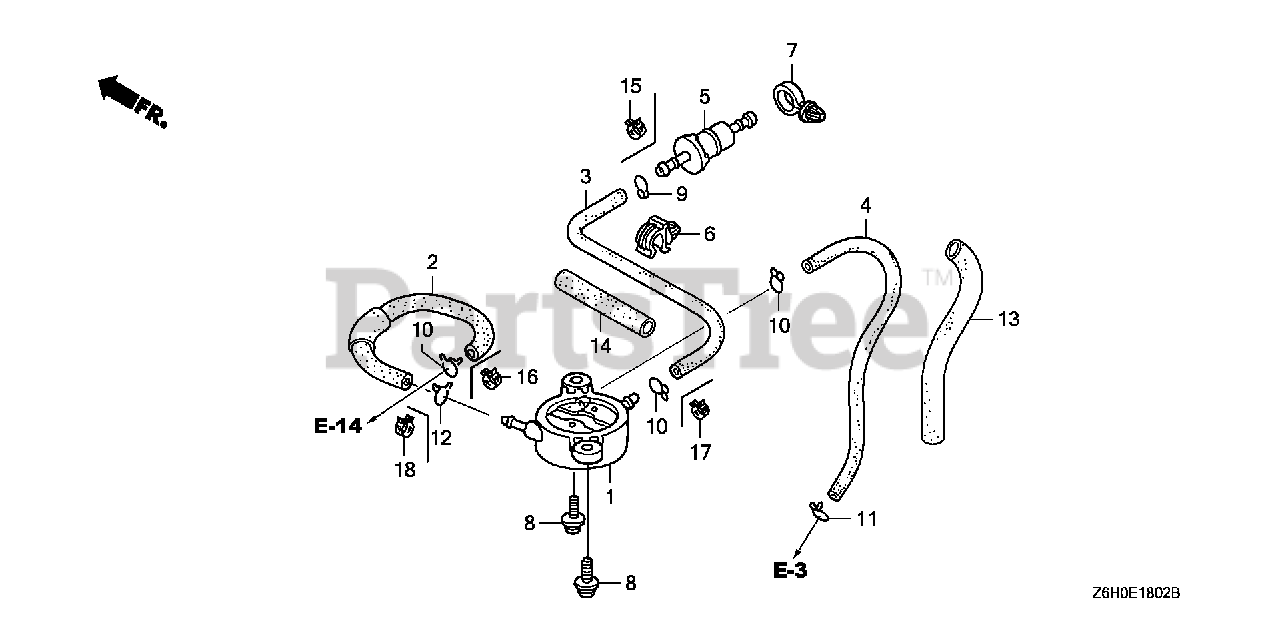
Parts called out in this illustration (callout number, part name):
1	PUMP ASSY., FUEL
2	TUBE, FUEL (FKM)
3	TUBE B, FUEL (FKM)
4	TUBE, DIAPHRAGM
5	STRAINER, FUEL
6	CLAMP, WIRE
7	CLIP, WIRE HARNESS
8	SCREW-WASHER (6X16)
10	CLIP, TUBE (B10)
11	CLIP, TUBE (B8)
13	BULK HOSE, VINYL (9X11X3000) (9X11X150)
14	BULK HOSE, VINYL (11X13X3000) (11X13X90)
15	CLAMP, TUBE (D8)
16	CLAMP, TUBE (D10)
17	CLAMP, TUBE (D8.5)
18	CLAMP, TUBE (D10)
